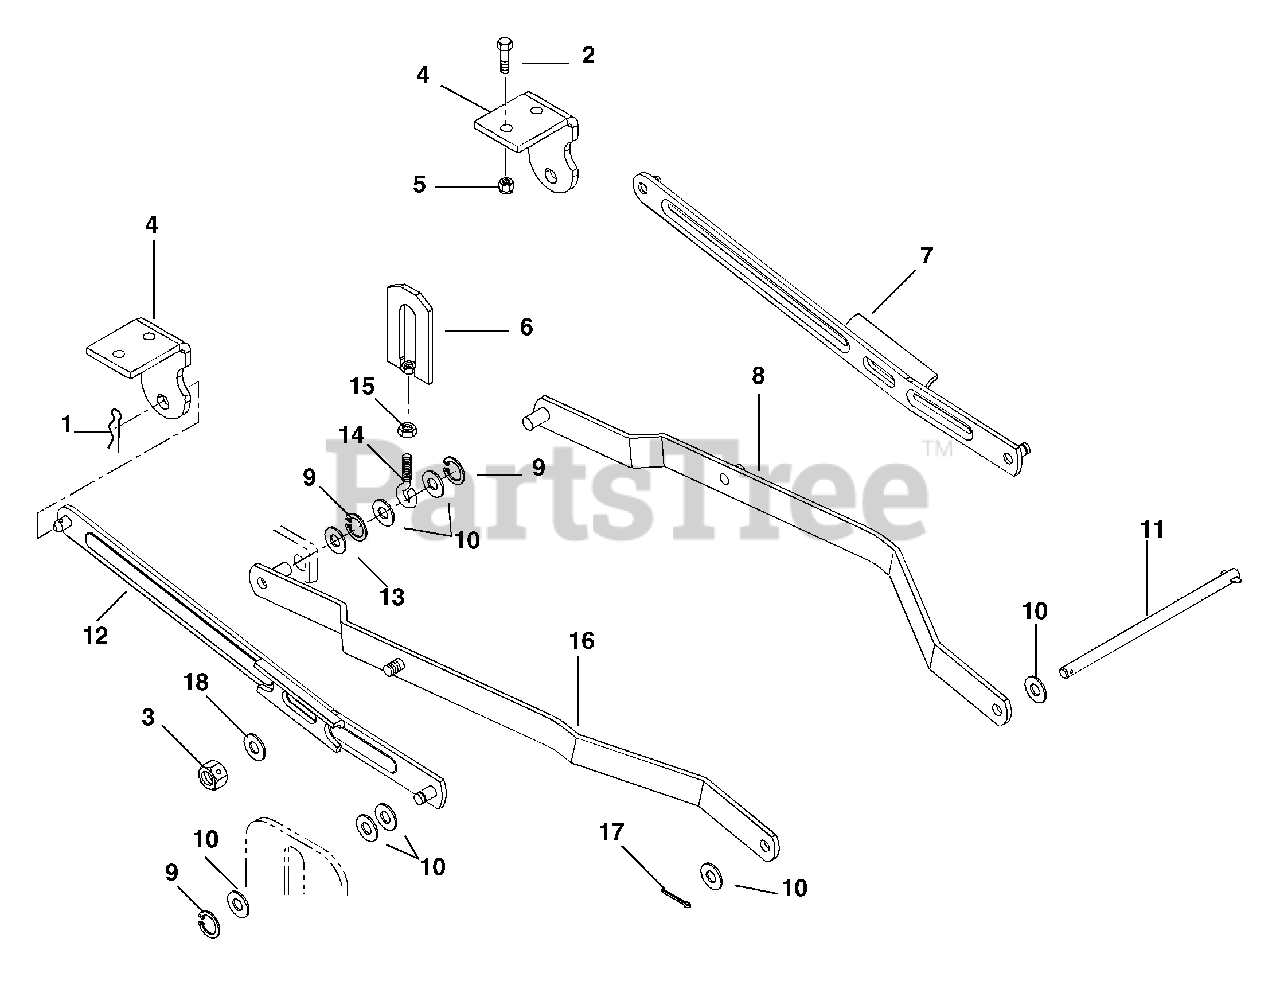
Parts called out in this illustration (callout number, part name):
1	Pin-Hair External .12 x .31 x 2.37
2	Bolt-Hex .38-16 x .75 Grade 5
3	Nut-Locking-Center .625-11
4	Rear Hanger
5	Nut-Locking-Center .375-16
6	Adjuster Link
7	Rear Hanger, Left Hand
8	Left Hand Lift Arm
9	Ring-Retaining-External .500 x .050
10	Washer-Flat-Steel .656 x .312 x .095
12	Rear Hanger, Right Hand
13	Washer-Flat-Steel .531 x 1.06 x .095
15	Nut-Jam .375-16
16	Right Hand Lift Arm
17	Pin-Cotter .12 x 1.0
18	Washer-Flat-Steel .656 x 1.31 x .095
